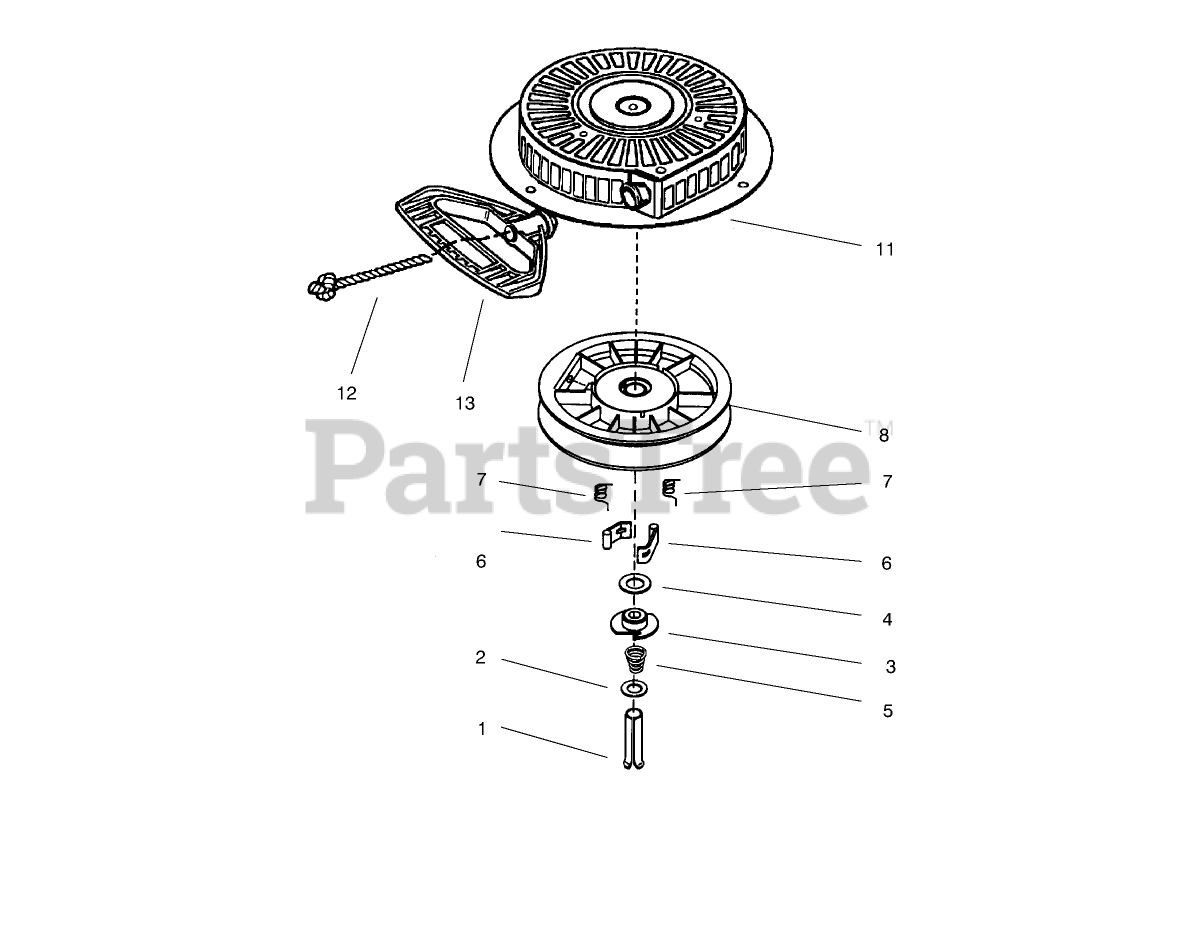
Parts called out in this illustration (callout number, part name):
1	Pin, Spring (Incl. Ref. #7)
2	Washer
3	Retainer
3	Handle-Starter, Mitten Grip
4	Washer
5	Spring-Brake
6	Dog-Starter
7	Spring-Dog
8	Pulley and Rewind Spring ASM
11	Starter Housing ASM
12	Rope-Starter (98 cut to length)
